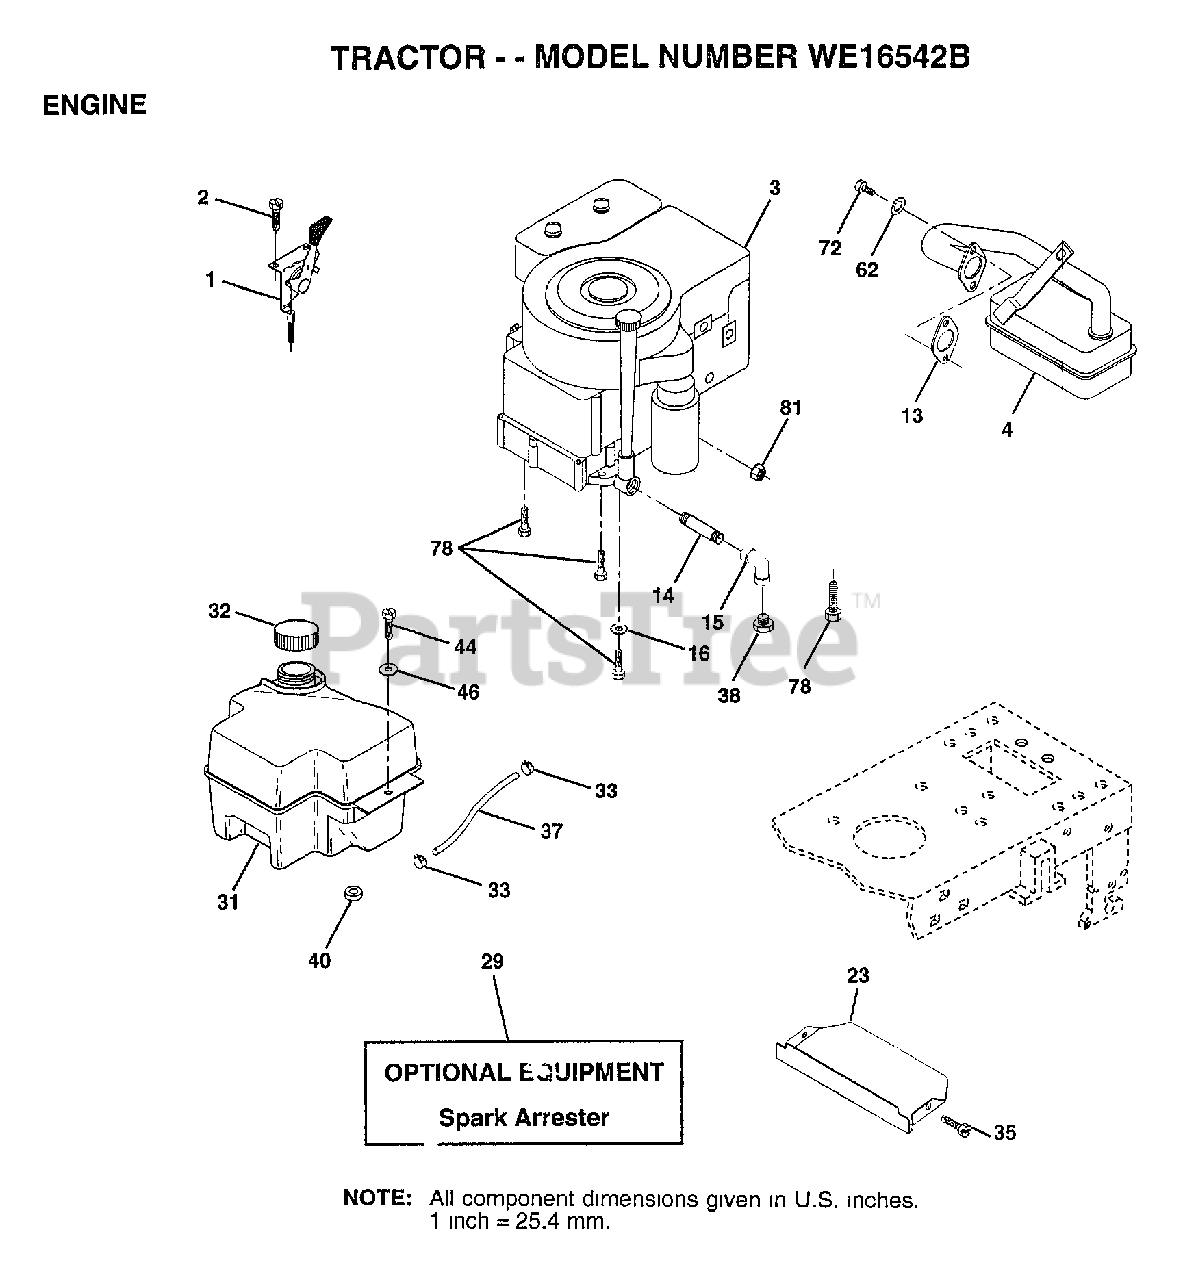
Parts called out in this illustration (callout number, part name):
1	CONTROL THROTTLE
2	SCREW LT
4	MUFFLER
14	PIPE NIPPLE
15	ELBOW
16	LOCKWASHER
23	SHIELD.BRN/DBR.GD
31	TANK.FUEL.FRONT.
32	CAP ASM FUEL
33	HOSE CLAMP
35	SCREW
37	LINE FUEL
44	SCREW HEX CRT
46	WASHER
62	LOCKWASHER
72	SCREW
78	SCREW
81	NUT
